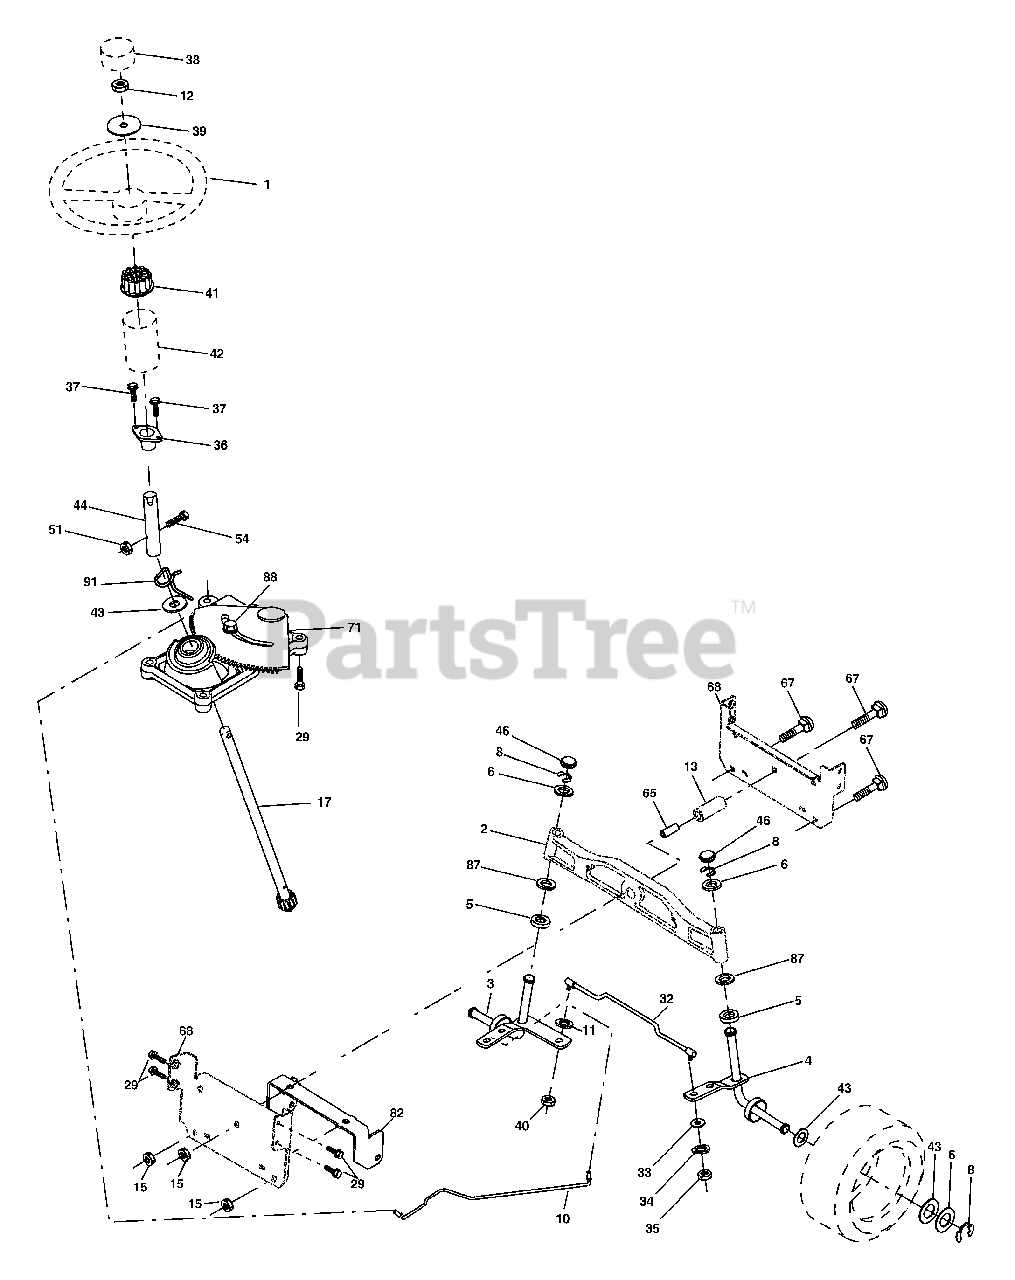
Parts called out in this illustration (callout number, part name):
1	Wheel Steering
2	Axle Asm Cast Iron LT
3	Spindle Asm LH
4	Spindle Asm RH
5	Bearing Race Thrust Harden
6	Washer 25/32 X 1-5/8 X 16 Ga
8	Ring Klip #t5304-75
10	Link Drag
11	Washer Lock Hvy Hlcl Spr 3/8
12	Nut 1/2-20 Unf
13	Spacer Brg. Axle Front
15	Nut Hex Flange Lock
17	Shaft Asm. Steering
29	Screw 3/8-16x.75
32	Rod Tie
33	Washer 11/32 x 3/4 x 16 Ga.
34	Washer Lock Hvy Hlcl Spr 5/16
35	Crownlock Nut 5/16-24
36	Bushing Strg
37	Screw
38	Insert Cap Strg Wh Au
39	Washer 9/16 x 1-1/2
40	Locknut
41	Adaptor Wheel Strg
42	Boot Steering Dash
43	Washer 25/32 X 1 1/4 X 16 Ga
44	Extension Steering Shaft
46	Cap Spindle Fr Top Blk
51	Nut 1/4-28
54	Bolt 1/4-28 x 1-1/4 Unf
65	Brace Axle
67	Bolt Rdhd Sq 3/8-16 Unc x 2-1/4
68	Axle, Brace
71	Steering Asm.
82	Bracket Susp. Chassis Front
87	Washer Flat .781 x 1-1/2 x .14
88	Bolt Shoulder 7/16-20 Unc
91	Clip Steering
